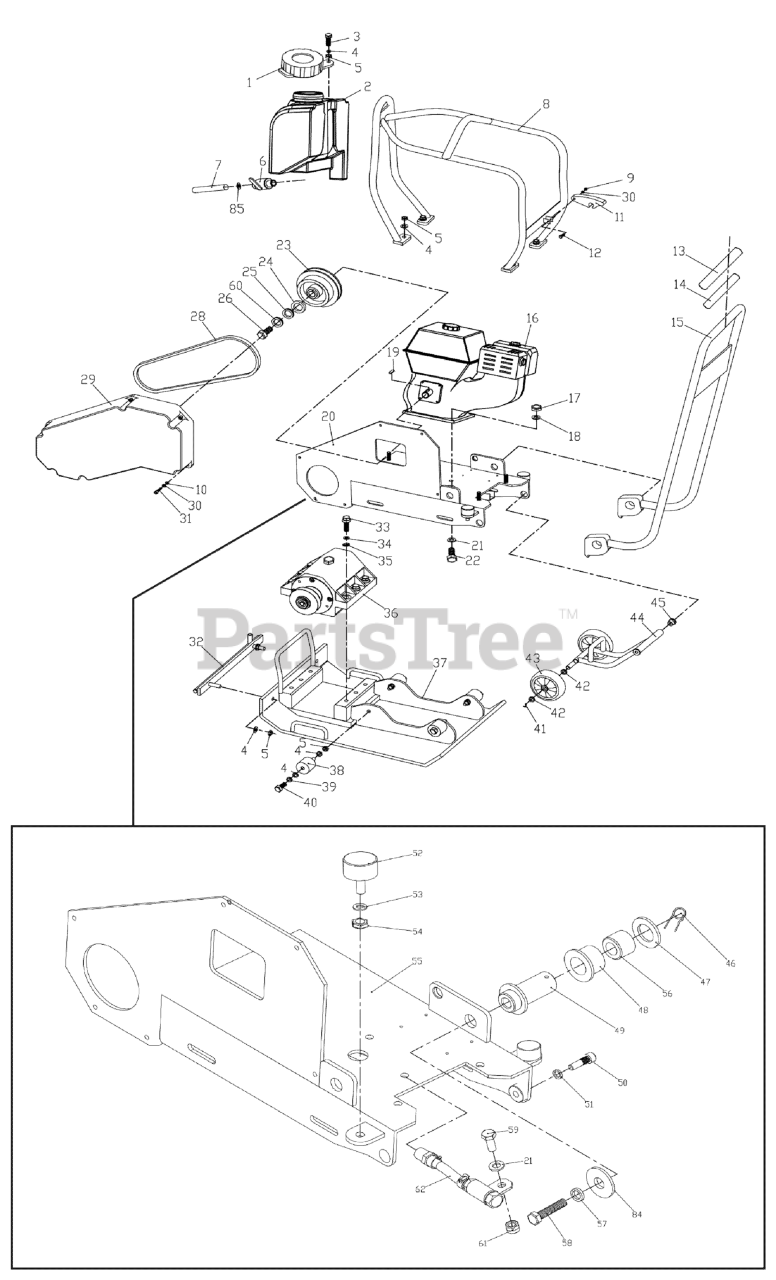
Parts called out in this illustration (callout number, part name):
1	COVER, Water Tank
2	WATER TANK
3	BOLT, Hex Head, M10 x 30
4	WASHER, 10
5	NUT, Hex Lock, 10
6	BALL VALVE, Brass, 1/4"
7	HOSE, Rubber, 14 x 3
8	HOOK, Guard
9	NUT, Hex Lock, M6
10	WASHER, Spring, 6
11	CLIP, Rubber
12	BOLT, Hex Head, M6 x 35
13	FOAM, Handle
14	SHEATH, Handle
15	HANDLE
16	ENGINE, Briggs & Stratton
17	NUT, Hex Lock, M8
18	WASHER, Flat, 8
19	KEY, 5 x 32
20	BASE ASSEMBLY, Engine
21	WASHER, Flat, 8
22	BOLT, Hex Head, M8 x 45
23	CLUTCH ASSEMBLY
24	BUSHING, Key
25	GASKET, Shaft
26	BOLT, Hex Head, M8 x 30
28	V-BELT, Red
29	COVER, Belt, PC4012
30	WASHER, Flat, 6
31	SCREW, Hexagon Socket, M6 x 25
32	WATER HOSE ASSEMBLY
33	BOLT, Hex Head, M12 x 40
34	WASHER, Spring, 12
35	WASHER, Flat, 12
36	ECCENTRIC BOX ASSEMBLY
37	BASE PLATE ASSEMBLY
38	VIBRATION Mount, Rubber, PC4012
39	WASHER, Spring, 10
40	BOLT, Hex Head, M10 x 20
41	SPLIT PIN
42	WASHER, Nylon, PC4012
43	WASHER, Nylon, PC4012
44	FRAME, Road Wheel
45	BUSHING, Nylon, PC4012
46	RETAINER RING
47	WASHER
48	BUSHING, Nylon
50	BOLT, Locking
51	WASHER, Spring, 12
52	VIBRATION Mount, Rubber
53	WASHER, Flat, 10
54	NUT, Hex Lock, 10
55	BASE, Engine
56	VIBRATION BUSHING ASSEMBLY
57	WASHER, Spring, 10
58	BOLT, Hex Head, M10 x 20
59	BOLT, Hex Head, M8 x 25
59	BOLT, Hex Head, M8 x 20
60	WASHER, Spring, 8
61	NUT, Hex Lock, M8
62	OIL DRAIN HOSE ASSEMBLY
84	WASHER
85	CLAMP
